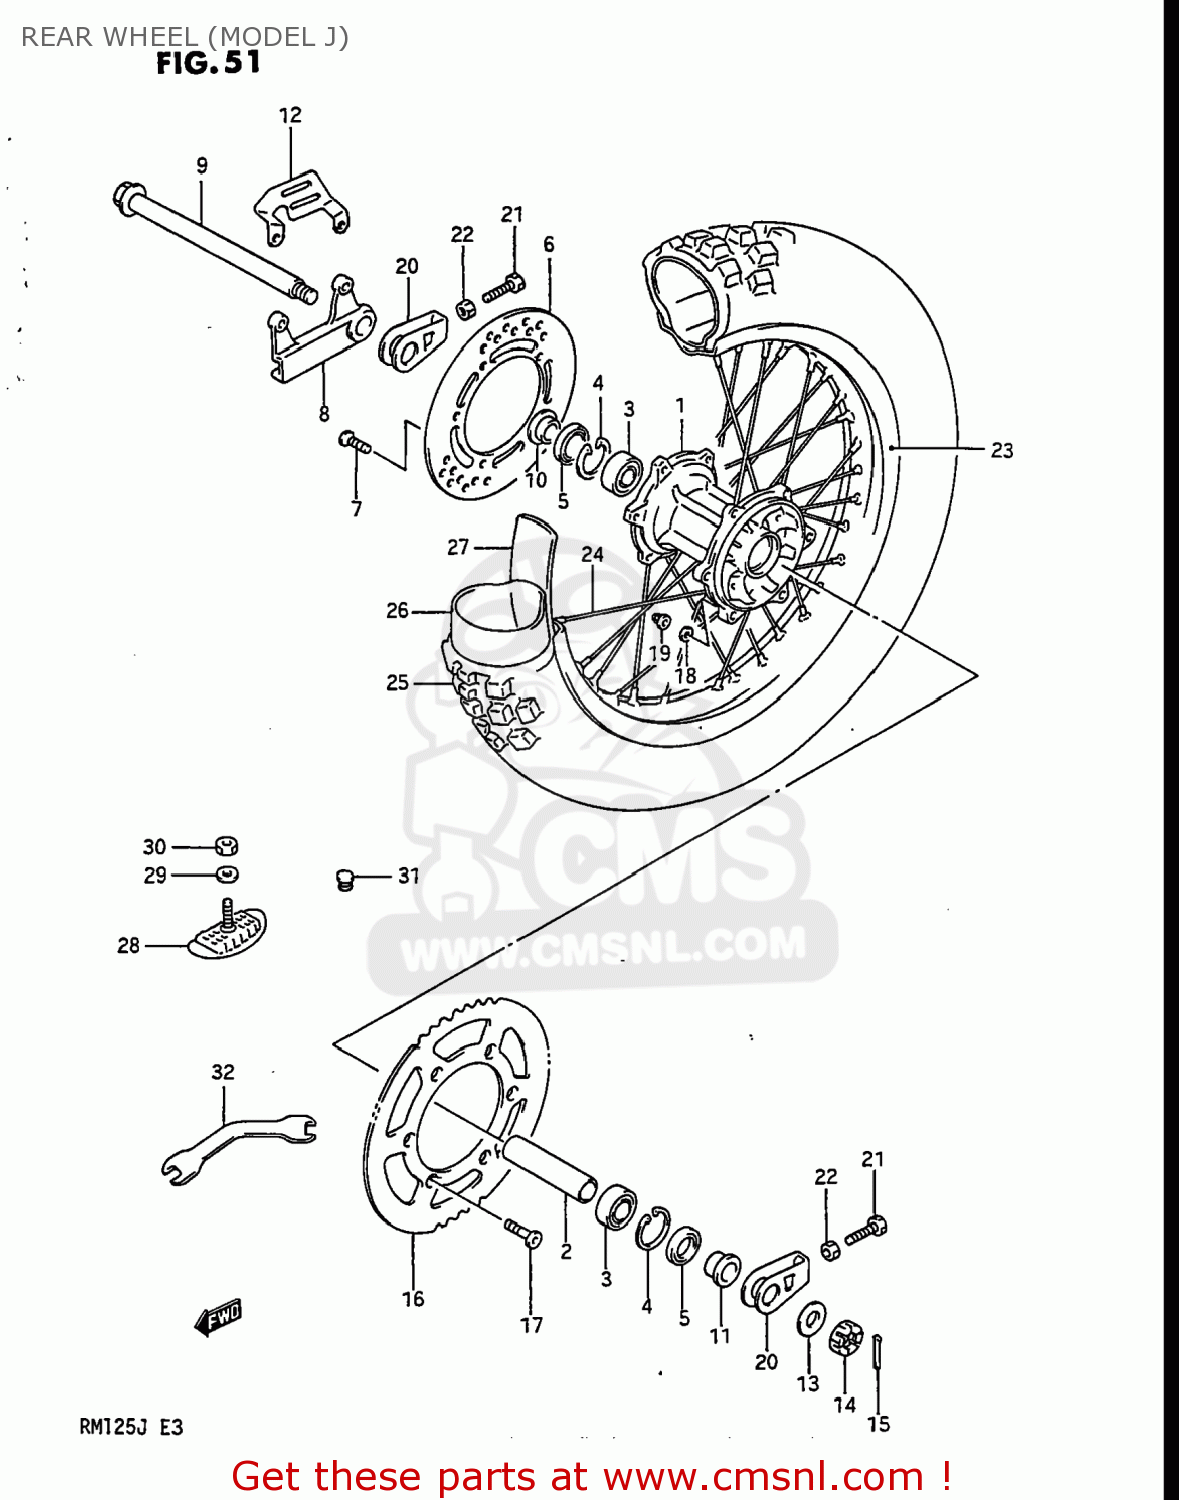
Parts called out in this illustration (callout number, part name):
1	HUB,REAR WHEEL
2	SPACER,RR HUB BEARING
3	BEARING
4	CIRCLIP,14MM
5	OIL SEAL
6	DISC,REAR BRAKE
7	SCREW
8	BRACKET,REAR CALIPER
9	AXLE,RR
10	SPACER,RR AXLE,R
11	SPACER,REAR AXLE,LEFT
12	GUARD,REAR CALIPER
13	WASHER (19X32X3.2)
14	NUT 18MM
15	PIN,COTTER
16	SPROCKET,REAR
17	SCREW(8X33.5)
18	WASHER
19	NUT
20	ADJUSTER COMP,CHAIN
21	BOLT L:50
22	NUT
23	RIM,REAR WHEEL (1.85X18)(A
24	SPOKE SET,REAR WHEEL
25	TIRE
26	TUBE ASSEMBLY,WHEEL,INNER
27	PROTECTOR
28	STOPPER,BEAD
29	WASHER
30	NUT 8MM
31	CAP(OD:12)
32	SPANNER,OPEN
